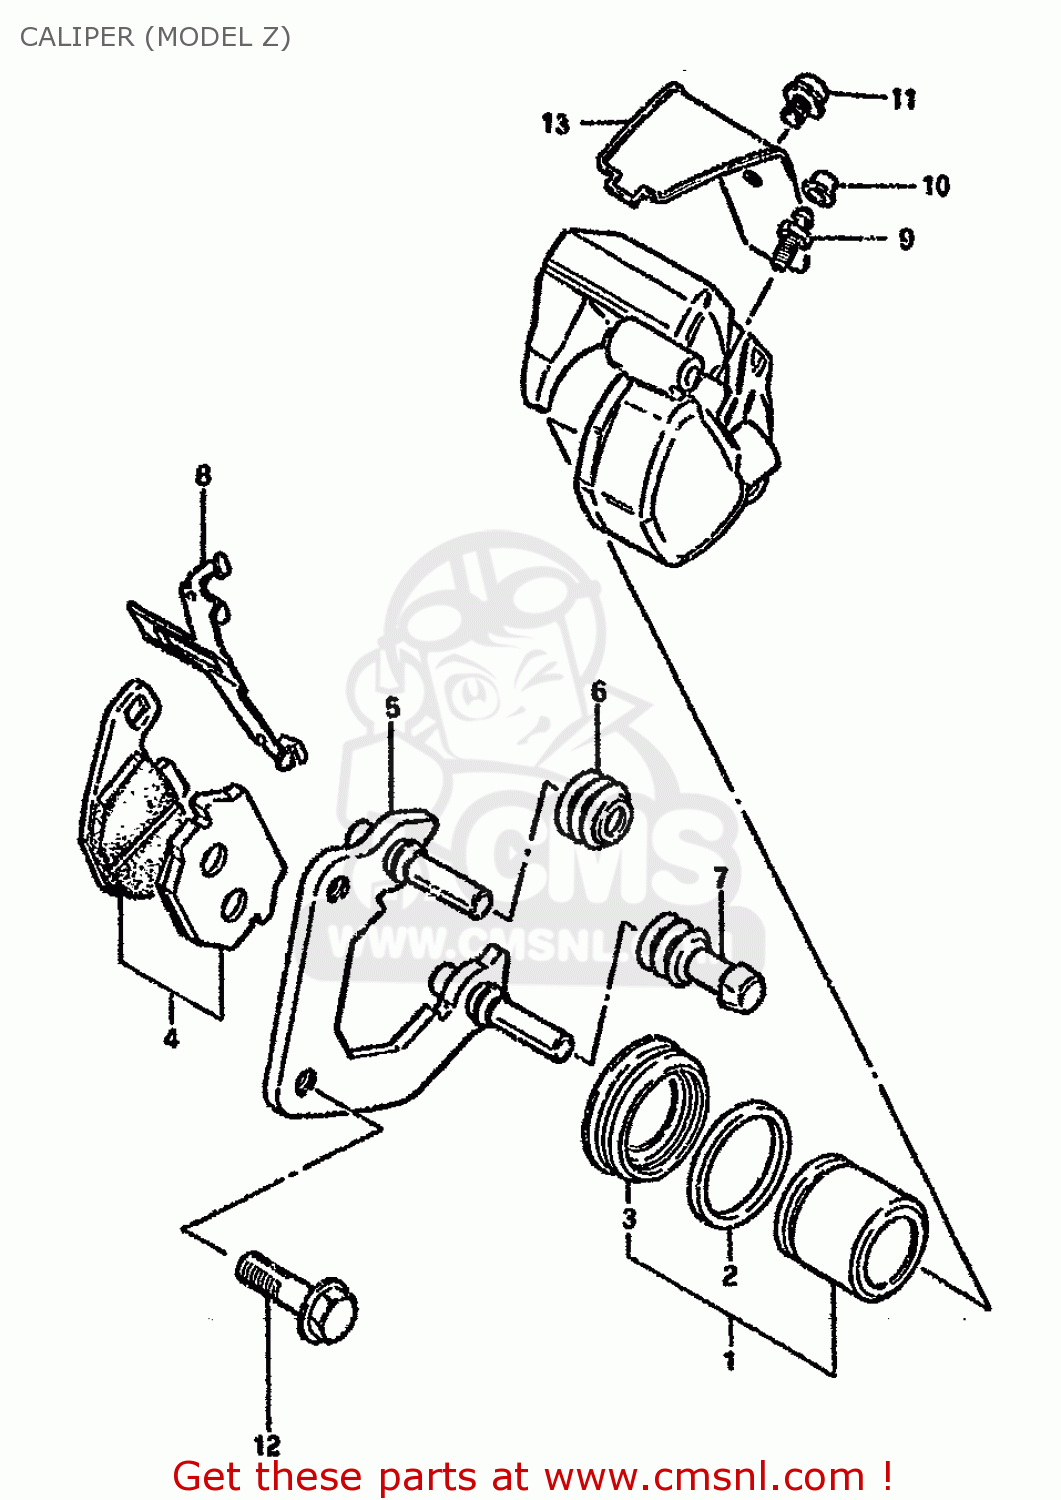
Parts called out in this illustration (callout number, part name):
1	PISTON SET
2	SEAL,PISTON
3	BOOT,PISTON
4	PAD SET,BRAKE (MCA)
5	CARRIER,L
6	BOOT,AXLE
7	INSULATOR,AXLE
8	SPRING,PAD
9	BLEEDER
10	CAP,BREATHER
11	SCREW
12	BOLT 8X30
13	PROTECTOR,CALIPER
